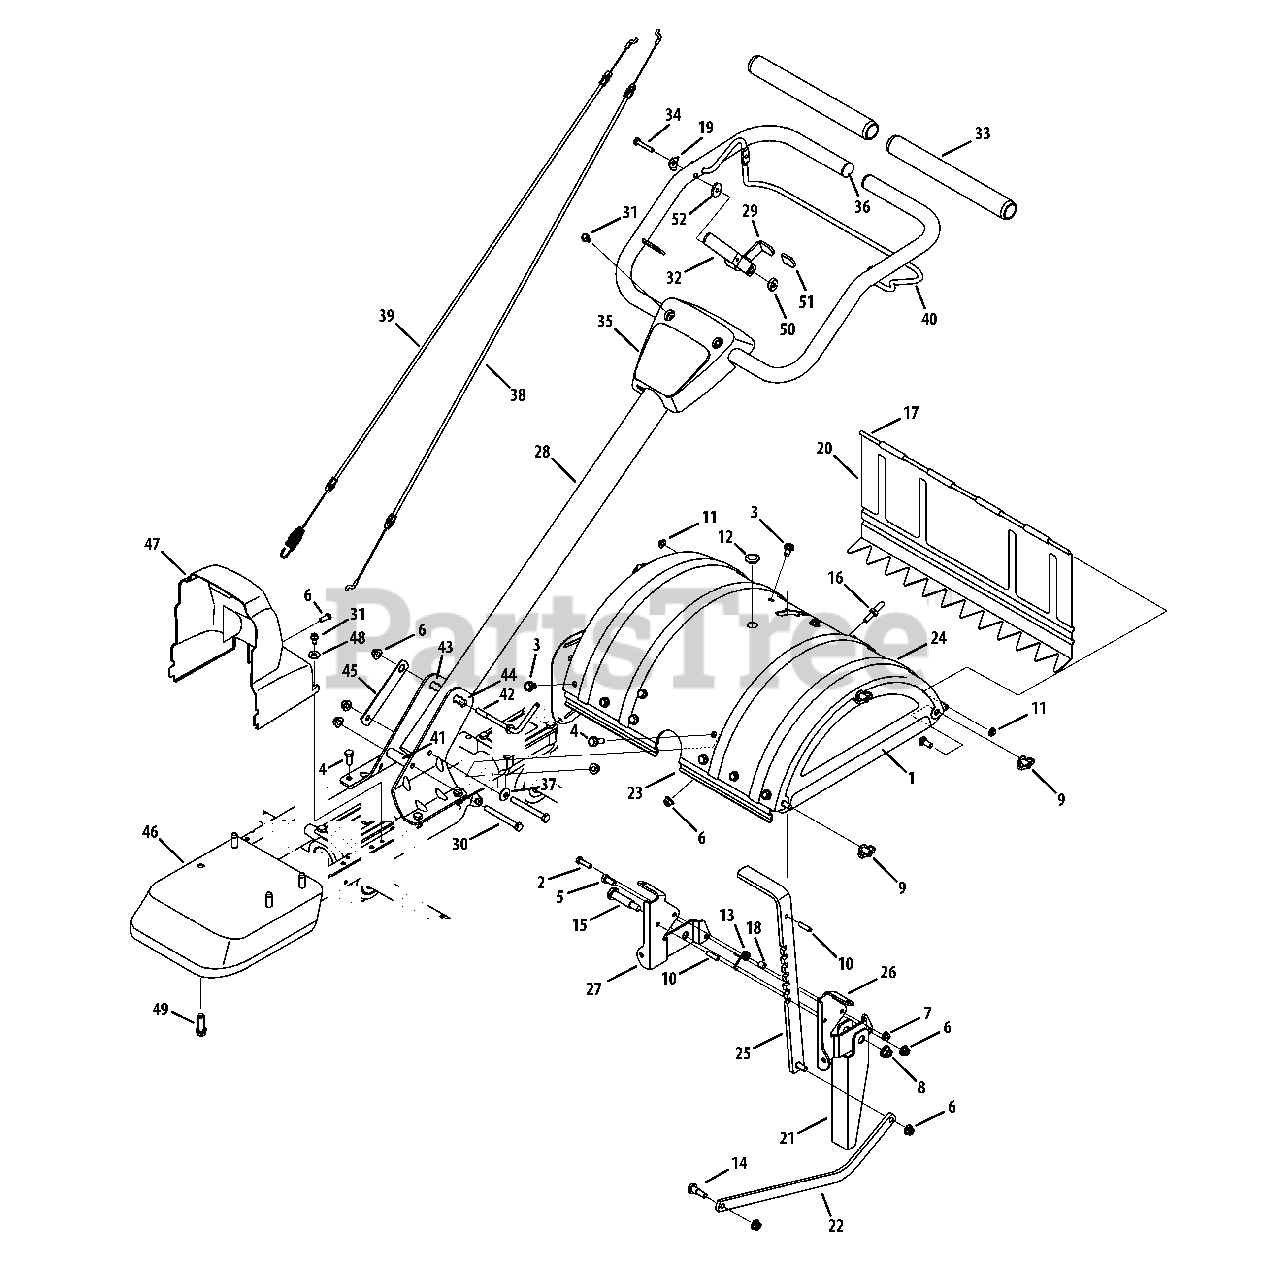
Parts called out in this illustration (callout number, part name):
1	End Cover Assembly
2	Hex Head Screw, 1/4-20 x 1
3	Hex Head Screw, 5/16-18 x .625
4	Hex Head Screw, 5/16-18 x .875
5	Hex Head Screw, 5/16-18 x .75
6	Self Tapping Screw, 1/4-14 x .625
7	Nylon Hex Lock Nut, 1/4-20
8	Flange Lock Nut, 3/8-16
9	Wing Nut, 5/16-18
10	Spirol Pin
11	Cap Nut, 1/4 Rod
12	Hole Plug
13	Torsion Spring
14	Shoulder Screw, .405 x .435 5/16-18
15	Shoulder Screw, .498 x 1.635
16	Stop Screw
17	Tiller Flap Rod
18	Spacer
19	Saddle Washer, .320 x .930 x .060
20	Rear Tine Shield
21	Reverse Stop Arm
23	Tine Shield Mounting Bracket
24	Tine Shield
25	Adjustable Depth Bar
26	Tail Bracket, LH
27	Tail Bracket, RH
28	Upper Handle Assembly
29	Reverse Handle Assembly
30	Hex Head Screw, 5/16-18 x 3.00
31	Self-Tapping Screw, 1/4-20 x 1/2
32	Handle Select
33	Foam Handle Grip
34	Hex Head Screw, 1/4-20 x 1.62
35	Handle Cover
36	Tine Shield Plug
37	Bell Washer, .340 x .872 x .060
38	Reverse Cable
39	Forward Cable
40	Clutch Bail
41	Spacer, .322 x .625 x 2.00
42	Handle Crank
43	Handle Bracket, RH
44	Handle Bracket, LH
45	Retainer Nut Bracket
46	Front Bumper
47	Belt Cover
48	Flat Washer, .28 x .74 x .063
49	SEMS Screw, 3/8-16
50	Spacer, .375 x .165
51	Reverse Handle Grip
52	Flat Washer, .265 x .938 x .120
